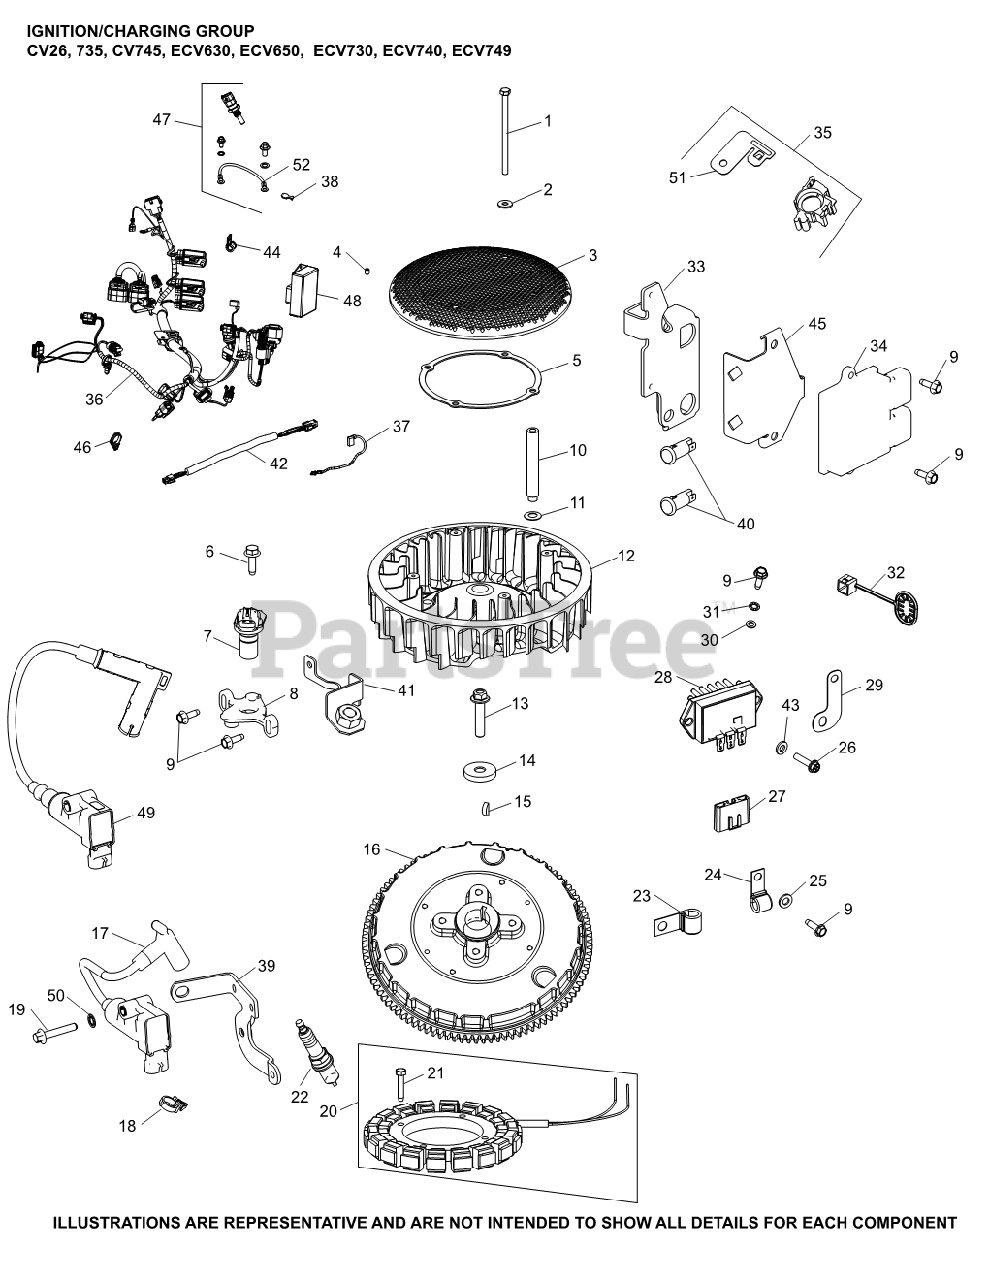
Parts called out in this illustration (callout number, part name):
1	SCREW, CAP M6X1.0X99.5
2	WASHER, FLAT 1/4" (O.D. 5/8")
3	SCREEN, GRASS
4	SCREW, SKT SET #10-24X1/4"
5	RING, SUPPORT USE 25 141 08-S
7	SENSOR, SPEED
9	SCREW, THREAD FORMING
11	WASHER, SPRING 10 MM
13	SCREW, FLG M10X1.5X45 - (#25086361S)
14	WASHER, FLAT 13/32"
15	KEY, 3/16" X 5/8"
16	FLYWHEEL, ASSEMBLY
17	COIL, IGNITION - EFI
19	SCREW, FLG M6X1.0X34
20	KIT, 15 / 20 AMP STATOR
21	SCREW, THREAD FORMING
22	PLUG, SPARK (STD)
26	SCREW, HEX FLANGE HI-LO
27	CONNECTOR
28	REGULATOR, RECTIFIER (20-30AMP,FW W/O USE 25 403 39-S
30	WASHER, FLAT 3/16"
31	WASHER, INT TOOTH LOCK #10
32	CAP, CONNECTOR
33	BRACKET, ECU
34	MODULE, ECU
35	KIT, MOUNTING CLIP
36	HARNESS, WIRING ASSEMBLY USE 24 176 258-S
51	CLIP, MOUNTING BRACKET USE 25 154 21-S
